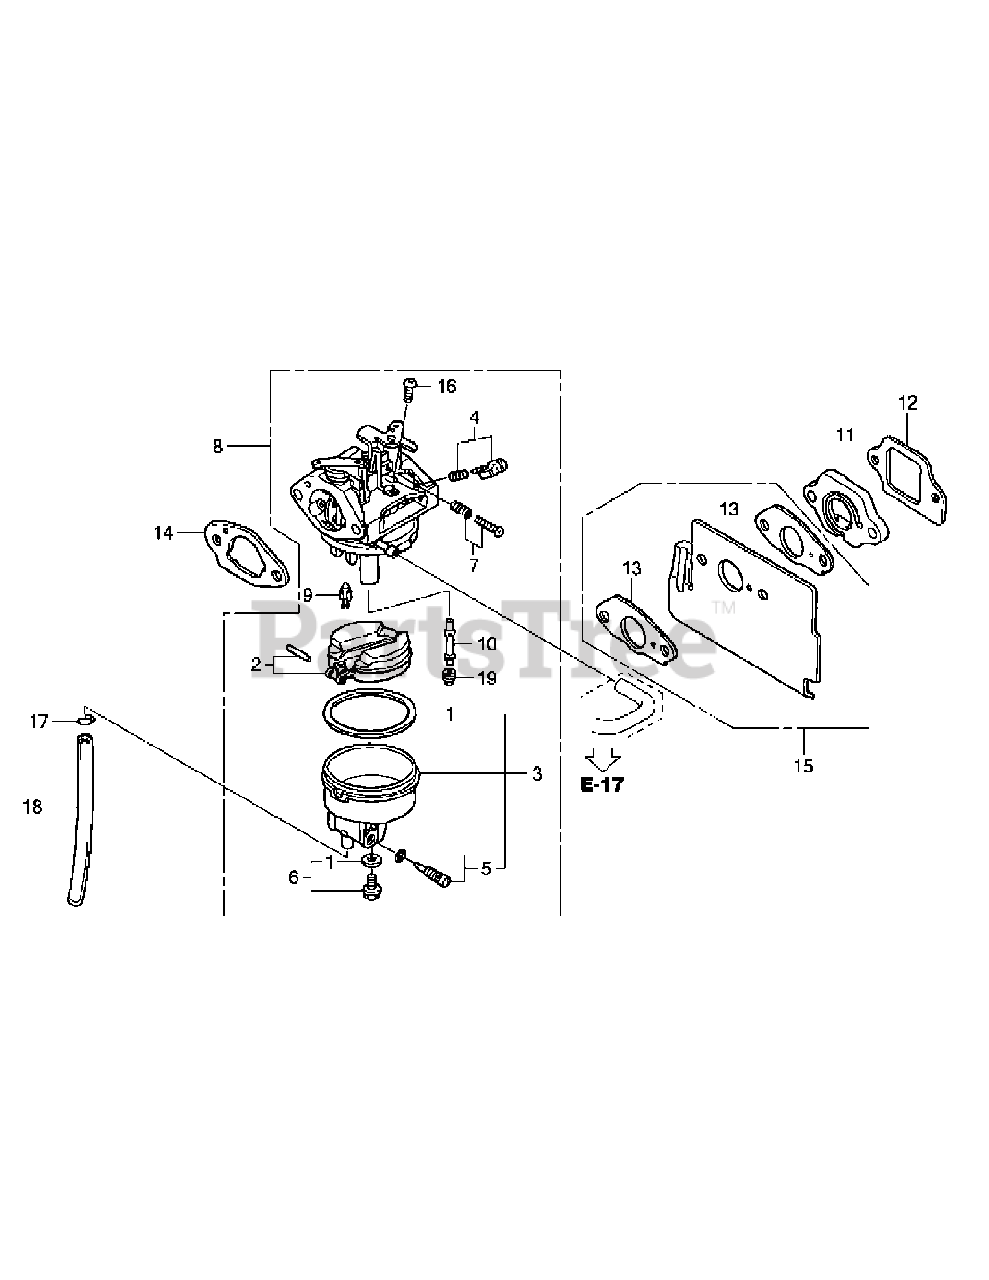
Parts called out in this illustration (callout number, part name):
1	Packing Set
3	Chamber Set, Float
5	Screw Set, Drain
6	Screw Set
7	Screw Set (Throttle Stop)
8	Carburetor Assy. (Bb61K A)
9	Valve Comp., Float
10	Nozzle, Main
11	Insulator, Carburetor
12	Packing, Insulator
13	Packing, Carburetor
14	Packing, Carburetor
15	Guide Comp., Air
16	Screw, Pan, 5X6
17	Clip, Tube (B6.5)
18	Tube, Vinyl, 4X7X150 (95003-07001-60M)
19	Jet, Main, #62
19	Jet, Main, #65
19	Jet, Main, #68
